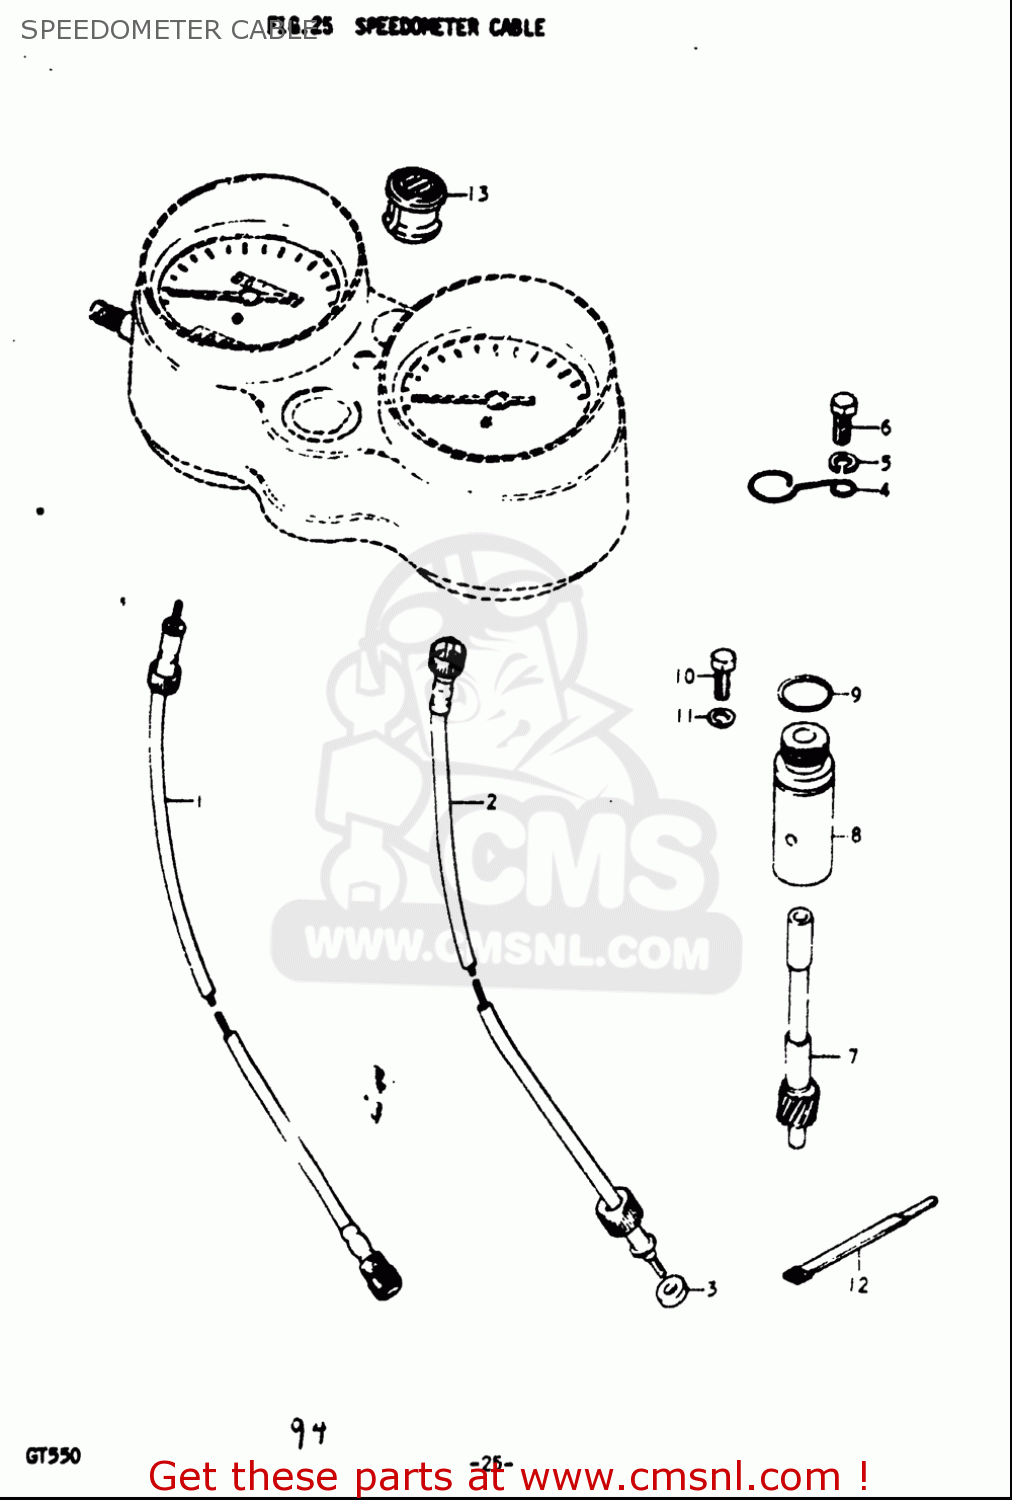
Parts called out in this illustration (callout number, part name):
1	CABLE ASSY,SPEEDOMETER
2	CABLE ASSY,TACHOMETER
3	SEAL,OIL SPEEDOMETER CABLE
5	WASHER,LOCK
6	BOLT
9	O RING(D:1.7,ID:15.5)
10	BOLT
11	WASHER
12	CLIP
13	CAP,SPEED WARNER LAMP HOLE
